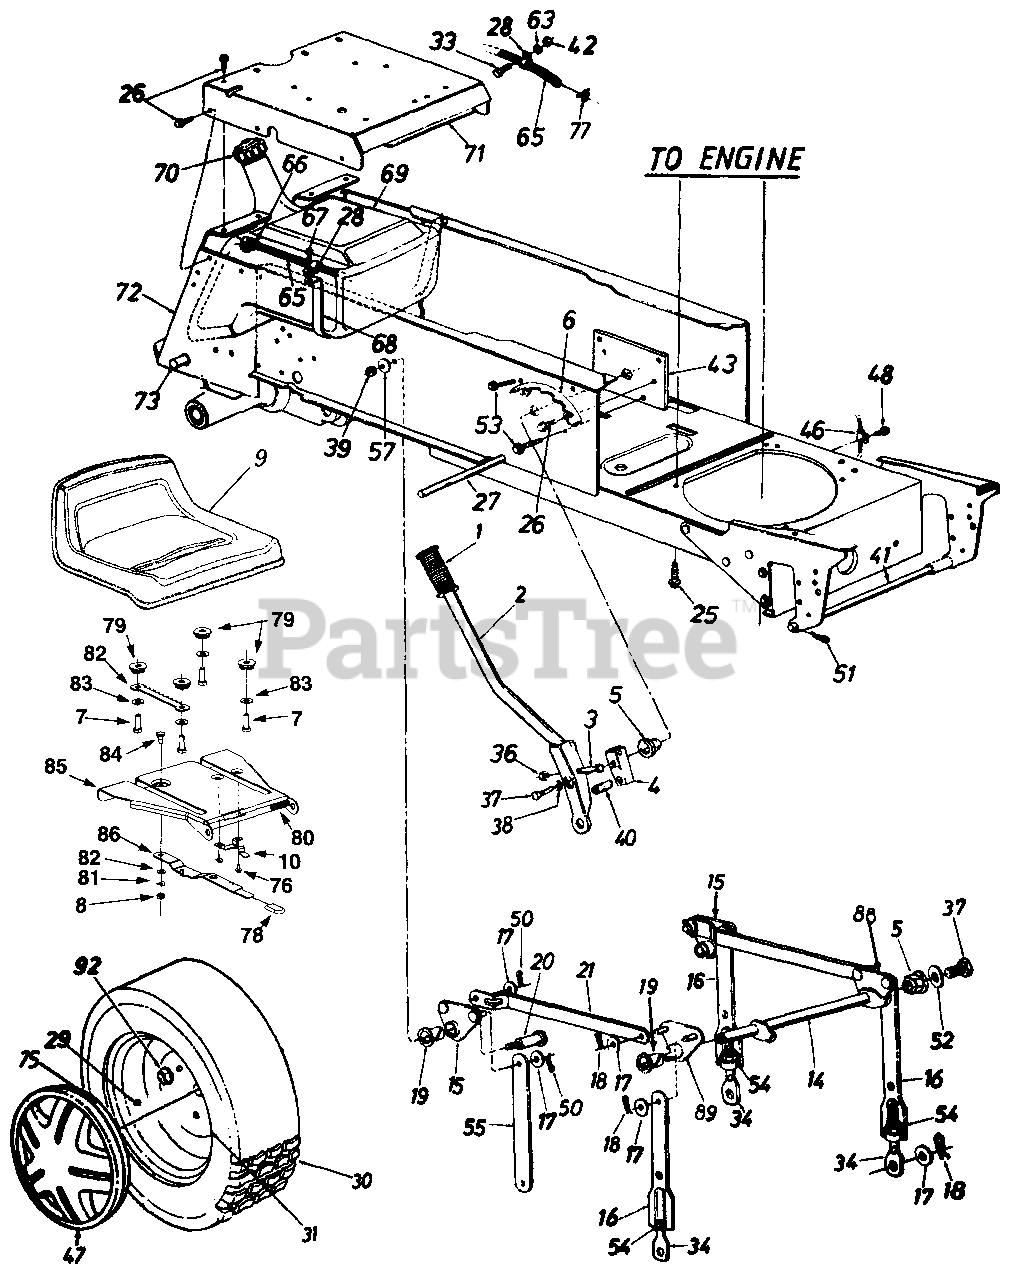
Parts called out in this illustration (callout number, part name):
1	Grip
2	Lift Handle Ass'y.
3	Hex Bolt 5/16-18 x 1.5" Lg.
4	Lift Shaft Drive
5	Plastic Hex Brg. 5/8" I.D.
8	Hex Flanged L-Nut 1/4-20 Thd.
9	Seat
10	Seat Stop
14	Lift Shaft Ass'y.
15	Lift Pivot Brkt. Ass'y.
17	Fl-Wash. 1/2" I.D. x 1.00" O.D. x .090"
18	Hairpin Cotter
19	Flanged Brg. 5/8" I.D.
20	Shld. Bolt 5/8" Dia. x .96" Lg. 3/8-16
26	Hex Thd. Rolling Scr. 5/16-18 x .75"
27	Running Board Rod
28	Clamp
29	Air Valve
33	Hex Bolt 1/4-20 x .62" Lg.
34	Eye Bolt Adj. Link 1/2-13 Thd.
36	Hex Cent. L-Nut 5/16-18 Thd.
37	Hex Bolt 5/16-24 x .75" Lg. (Gr. 5)
39	Hex Top L-Nut 3/8-16 Thd.
40	Compression Spring
41	Deck Connecting Rod
42	Hex Sems Nut 1/4-20 Thd.
47	Hub Cap
48	Hex Wash. Hd. TT-Tap Scr.
50	Cotter Pin .09 Dia. x 1.0" Lg.
51	Int. Cotter Pin
52	Flat Wash. .34" I.D. x 1.12" O.D.
53	Hex Wash. Hd. AB-Tap Scr.
54	Hex Nut 1/2-13 Thd.
57	Bell-Wash. .4" I.D. x 1.13" O.D.
63	L-Wash. 1/4" I.D.
65	Fuel Line 46" Lg.
66	Hose Clamp
67	Hex AB-Tap Scr. 1/4 x .62" Lg.
68	Fuel Tank Strap
69	Gas Tank
70	Gas Gauge
71	Seat Plate
75	Spring Clip
76	Hex Wash. Hd. Tap Scr.
77	Hose Clamp
78	Seat Adjustable Grip
79	Spacer
80	Compression Spring
81	Spring Wash. .265" I.D.
82	Fl-Wash. .344" I.D.
83	Fl-Wash. .406" I.D.
84	Shld. Bolt .34" x 1/4-20 Thd.
88	Lift Pivot Brkt. - L.H.
89	Lift Pivot Brkt. - R.H.
92	Lug Nut 7/16-14 Thd.
